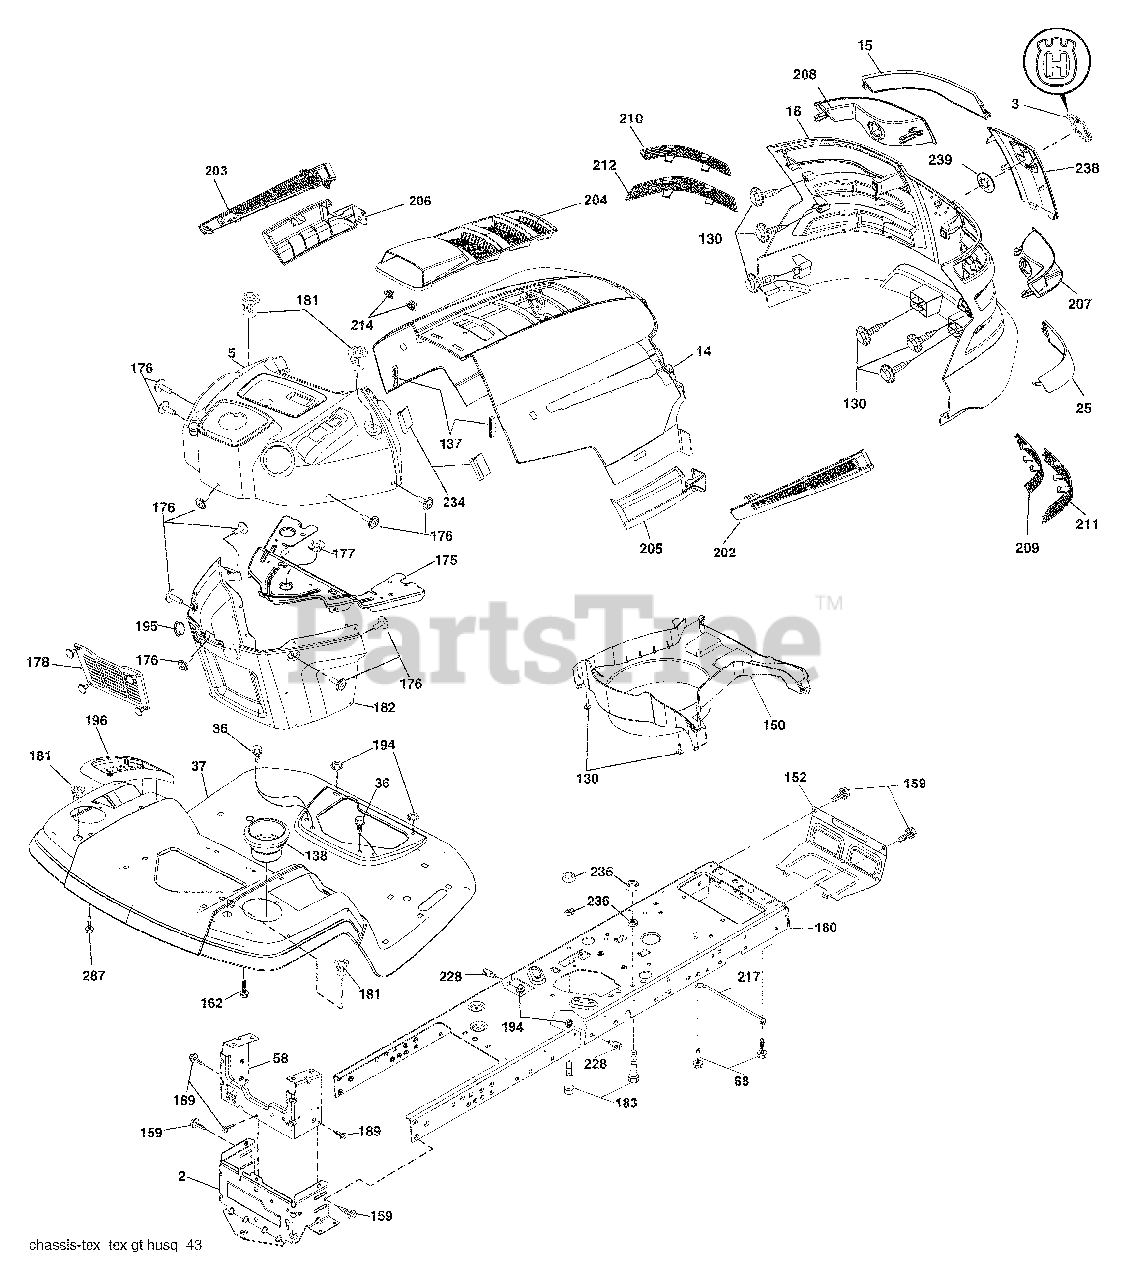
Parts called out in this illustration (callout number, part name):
2	Drawbar Lower
3	Logo
14	Hood
18	Grille/Lens Asm.
36	Screw 5/16-18 x 3/4
37	Fender
58	Drawbar Upper 2PC Sml. Fender
68	Screw Thdrol 5/16-18 x 1/2
130	Screw #10 x 0.750
137	Bumper Dash
138	Cupholder
152	Shield Browning
159	Screw 3/8-16 x 3/4
175	Crossmember
176	Screw 10-24 x 5/8
177	Bushing Steering
178	Cargo Net Asm.
180	Chassis
181	Bushing Mtg. Fender Crgo
182	Dash Lower
183	Bolt Fin Hex 5/16-18 unc x 1-1/4
189	Screw 5/16-18 x 3/4
194	Nut Lock Hex Flange 5/16-18
195	Plug Hole Dash Lower
196	Console Asm. Deck Lift
202	Vent Side Hood RH
203	Vent Side Hood LH
204	Vent Top Hood
205	Skirt Hood Side RH
206	Skirt Hood Side LH
209	Insert Hex Top RH
210	Insert Hex Top LH
211	Insert Hex Bottom RH
212	Insert Hex Bottom LH
214	Clip Retainer Tinner
228	Stud Fastner
234	Bumper Hood
235	Spacer Fender
236	Nut Lock 5/16-18 unc
287	Screw 1/4-20 x 3/8
